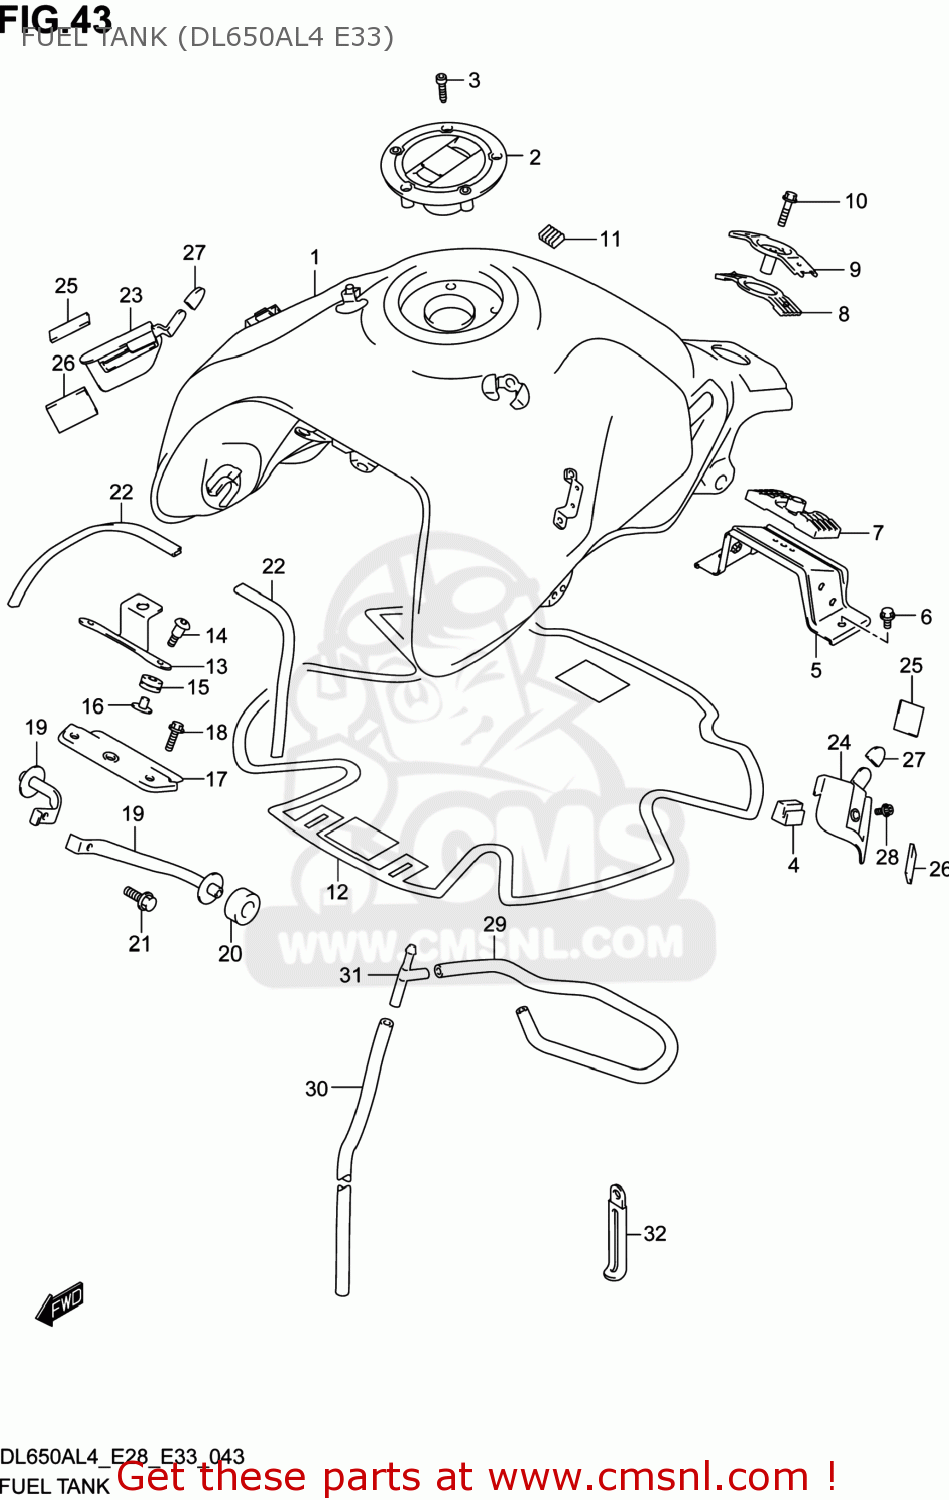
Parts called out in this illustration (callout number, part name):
1	TANK ASSY,FUEL(BLACK)
2	CAP SET,FUEL TANK
3	BOLT,FUEL TANK FILLER CAP
4	CUSHION,FUEL TANK SIDE
5	BRACKET,FUEL TANK RR
6	BOLT
7	CUSHION,FUEL TANK RR LWR
8	CUSHION,FUEL TANK RR UPR
9	BRACKET,FUEL TANK RR UP
10	BOLT
11	FASTENER
12	SHIELD,FUEL TANK CTR
13	BRACKET,FR COVER
14	SCREW(6X25)
15	CUSHION,FUEL TANK FR
16	SPACER,FUEL TANK FR
17	BRACKET,FUEL TANK FR
18	BOLT
19	BRACKET,FR SIDE
20	CUSHION,FR SIDE BRKT
21	BOLT
22	MOLDING,FUEL TANK
23	BRACKET,FUEL TANK COVER,R
24	BRACKET,FUEL TANK COVER,L
25	FASTENER
26	CUSHION,TANK SIDE COVER
27	CUSHION
28	BOLT
29	HOSE,FUEL TANK DRAIN NO.1
30	HOSE,FUEL TANK DRAIN NO.2
31	3 WAY
32	CLAMP(L:80)
